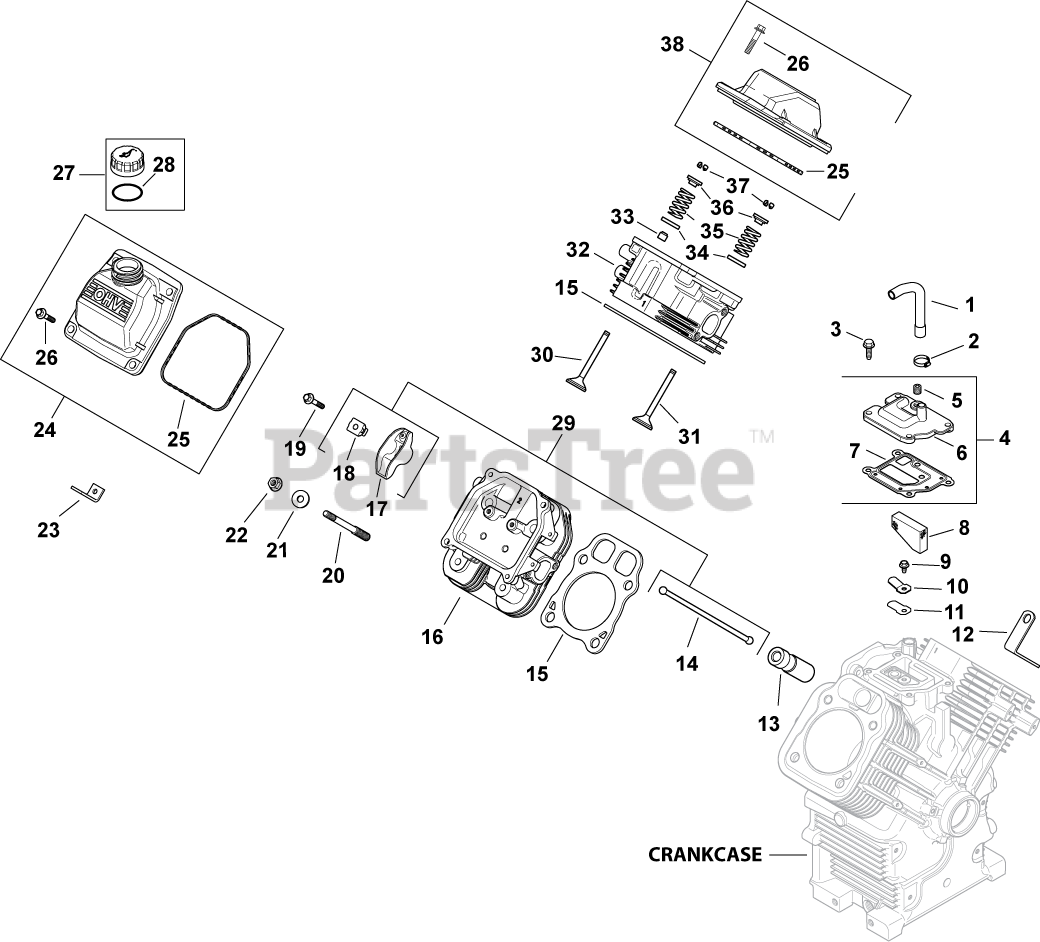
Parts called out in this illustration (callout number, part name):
1	HOSE, BREATHER
2	CLAMP, BAND SPRING HOSE-(#2523737S)
3	SCREW,FLG THD FRM M6X1.0X20-(#25086396S)
4	KIT, BREATHER ASSEMBLY
5	PLUG, CTSK PIPE 1/8"
6	COVER, BREATHER -USE 24 033 01-S
7	GASKET, BREATHER-USE 24 041 67-S
8	FILTER, BREATHER
9	SCREW, FLG THD FRM M5X.8X10
10	RETAINER, REED
11	REED, BREATHER
12	STRAP, LIFTING-USE 25 445 03-S
13	LIFTER, HYDRAULIC VALVE-USE 25 351 10-S
14	ROD, PUSH
15	CYL HEAD GASKET KIT-USE 24 841 04-S
16	HEAD, SERVICE ASSY CYL #2-USE 24 318 114
17	ARM, ROCKER
18	PIVOT, ROCKER ARM
19	SCREW, FLG M6X1.0X34
20	STUD, M8X1.25
21	WASHER, FLAT 8.6 MM
22	NUT, FLG M8X1.25
24	KIT, VALVE COVER-OIL FILL
25	O-RING (BLACK)
26	SCREW, FLG M6X1.0X30
27	KIT, OIL FILL CAP (YELLOW)
28	O-RING, DIPSTICK
29	KIT, VALVE TRAIN
30	VALVE, INTAKE (STD)
31	VALVE, EXHAUST (STD) - USE 32 016 01-S
32	HEAD, SERVICE ASSY CYL #1-USE 24 318 106
33	RETAINER, SPRING
34	SEAL, VALVE STEM - (#2503214S)
35	SPRING, VALVE
36	RETAINER, VALVE SPRING - USE 25 173 28-S
37	KIT, RETAINER
38	KIT, VALVE COVER-PLAIN
2401602-S	VALVE, EXHAUST (.25)
2401702-S	VALVE, INTAKE (.25)
